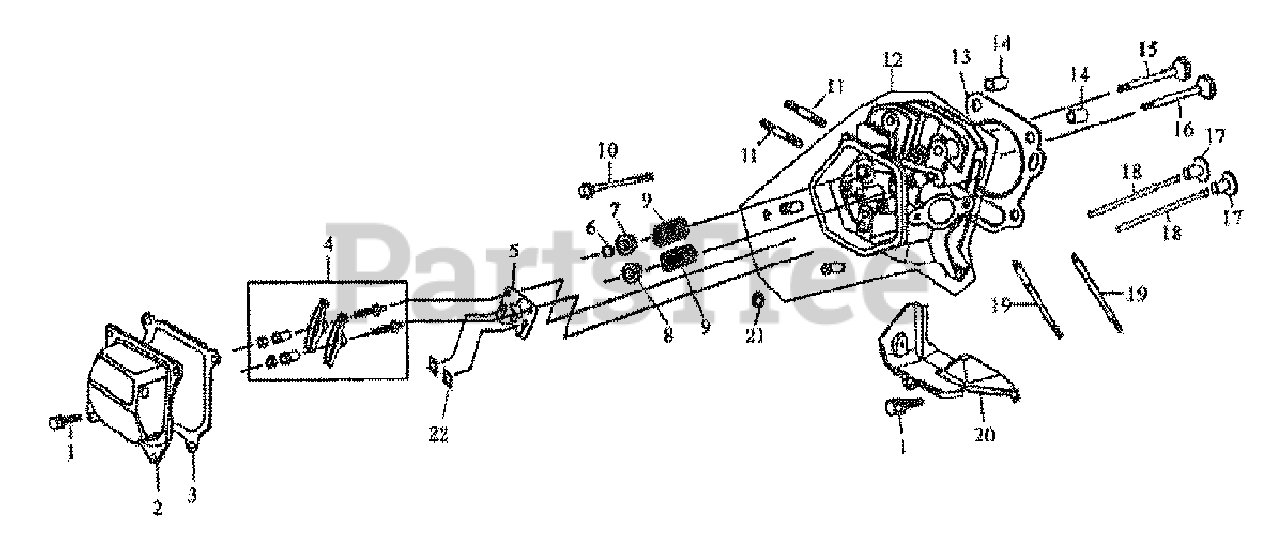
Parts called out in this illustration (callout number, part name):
1	BOLT' M6X12
2	COVER' CYLINDER HEAD
3	GASKET' CYLNDR HEAD CVR.
4	ROCKER ASSY' VALVE
5	GUIDE' PUSH
7	SEAT' EXHAUST SPRING
8	SEAT' INTAKE SPRING
9	SPRING' VALVE
10	BOLT' M8X60
11	STUD' AM 8X60
12	HEAD' CYLINDER
13	GASKET' CYLNDR HEAD
15	VALVE' EXHAUST
16	VALVE' INTAKE
18	ROD' PUSH
19	STUD' AM 6X112
20	COVER' LEAD WIND
21	SEAL' OIL PIPE
